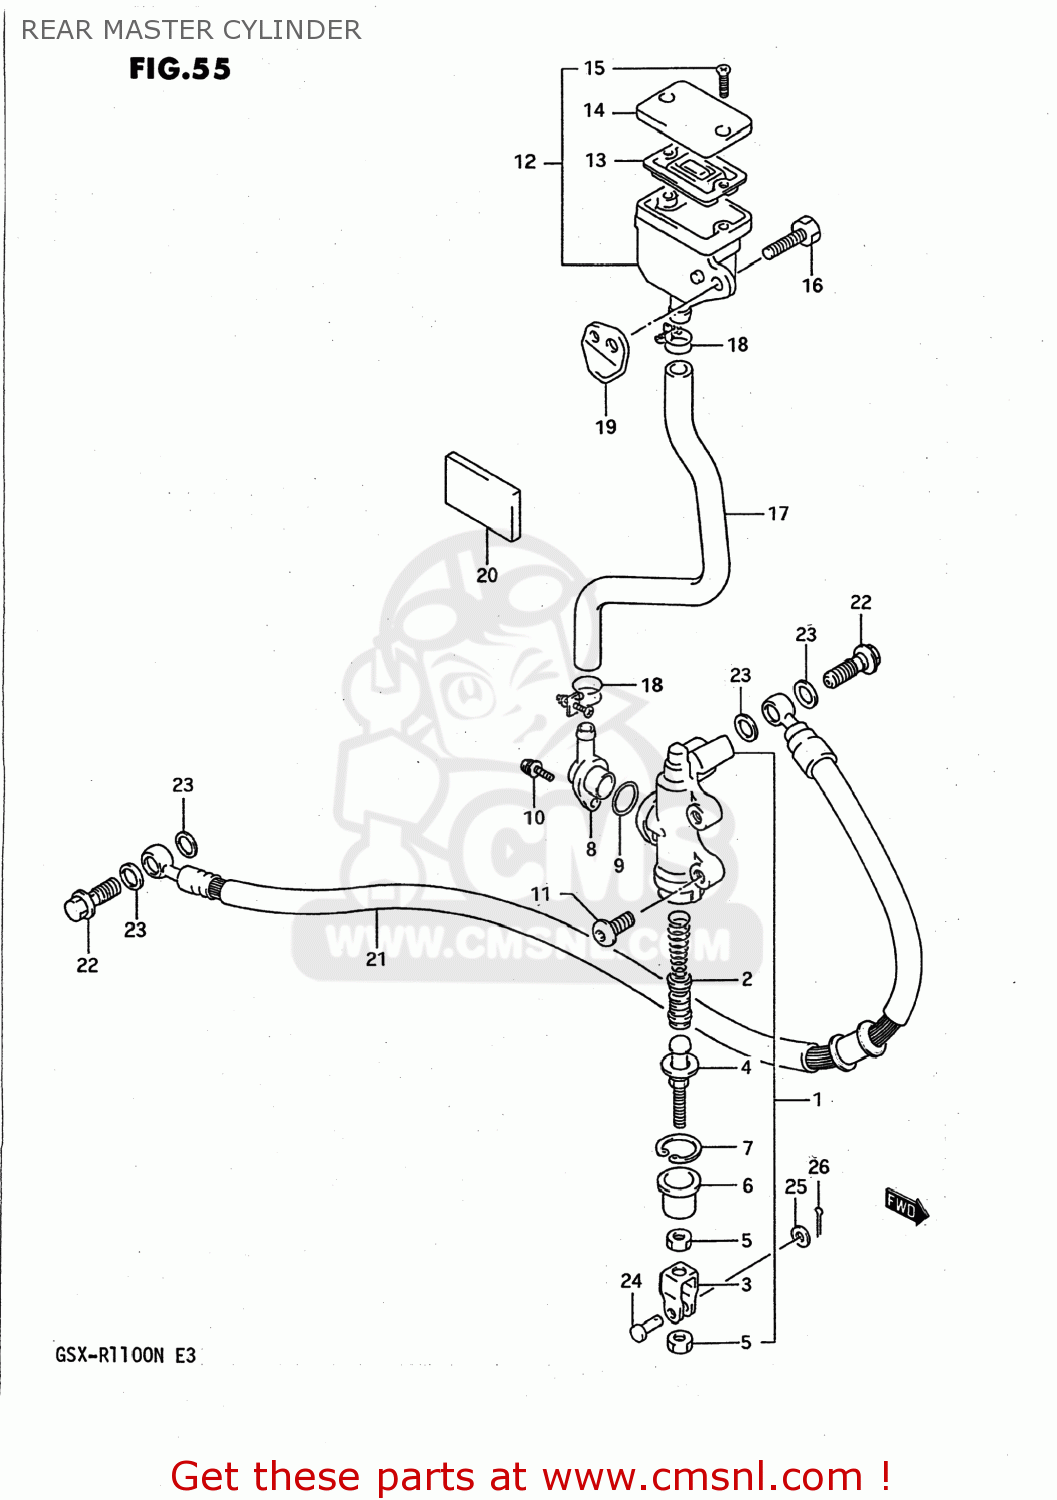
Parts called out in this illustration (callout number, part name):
1	CYLINDER ASSY,RR MASTER
2	PISTON/CUP SET
3	YOKE
4	ROD,PUSH
5	NUT
6	BOOT
7	CIRCLIP
8	CONNECTOR
9	O RING
10	SCREW
11	SCREW(8X22)
12	TANK ASSEMBLY,RESERVOIR
13	DIAPHRAGM
14	CAP
15	SCREW
16	BOLT
17	HOSE,RESERVOIR TANK
18	CLAMP
19	BRACKET,RESERVOIR TANK RR
20	CUSHION,PANEL
21	HOSE,REAR BRAKE
22	BOLT UNION
23	WASHER(10X15X1.5)
24	PIN
25	WASHER
26	PIN
